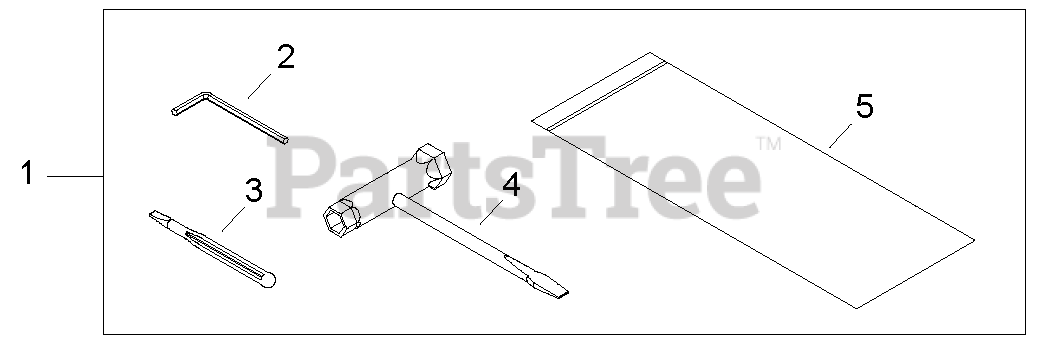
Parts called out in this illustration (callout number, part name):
1	TOOL KIT, SERVICE
2	WRENCH, ALLEN 4 MM
3	SCREWDRIVER, PLASTIC
4	T-WRENCH 13×19 MM
5	BAG, TOOL
